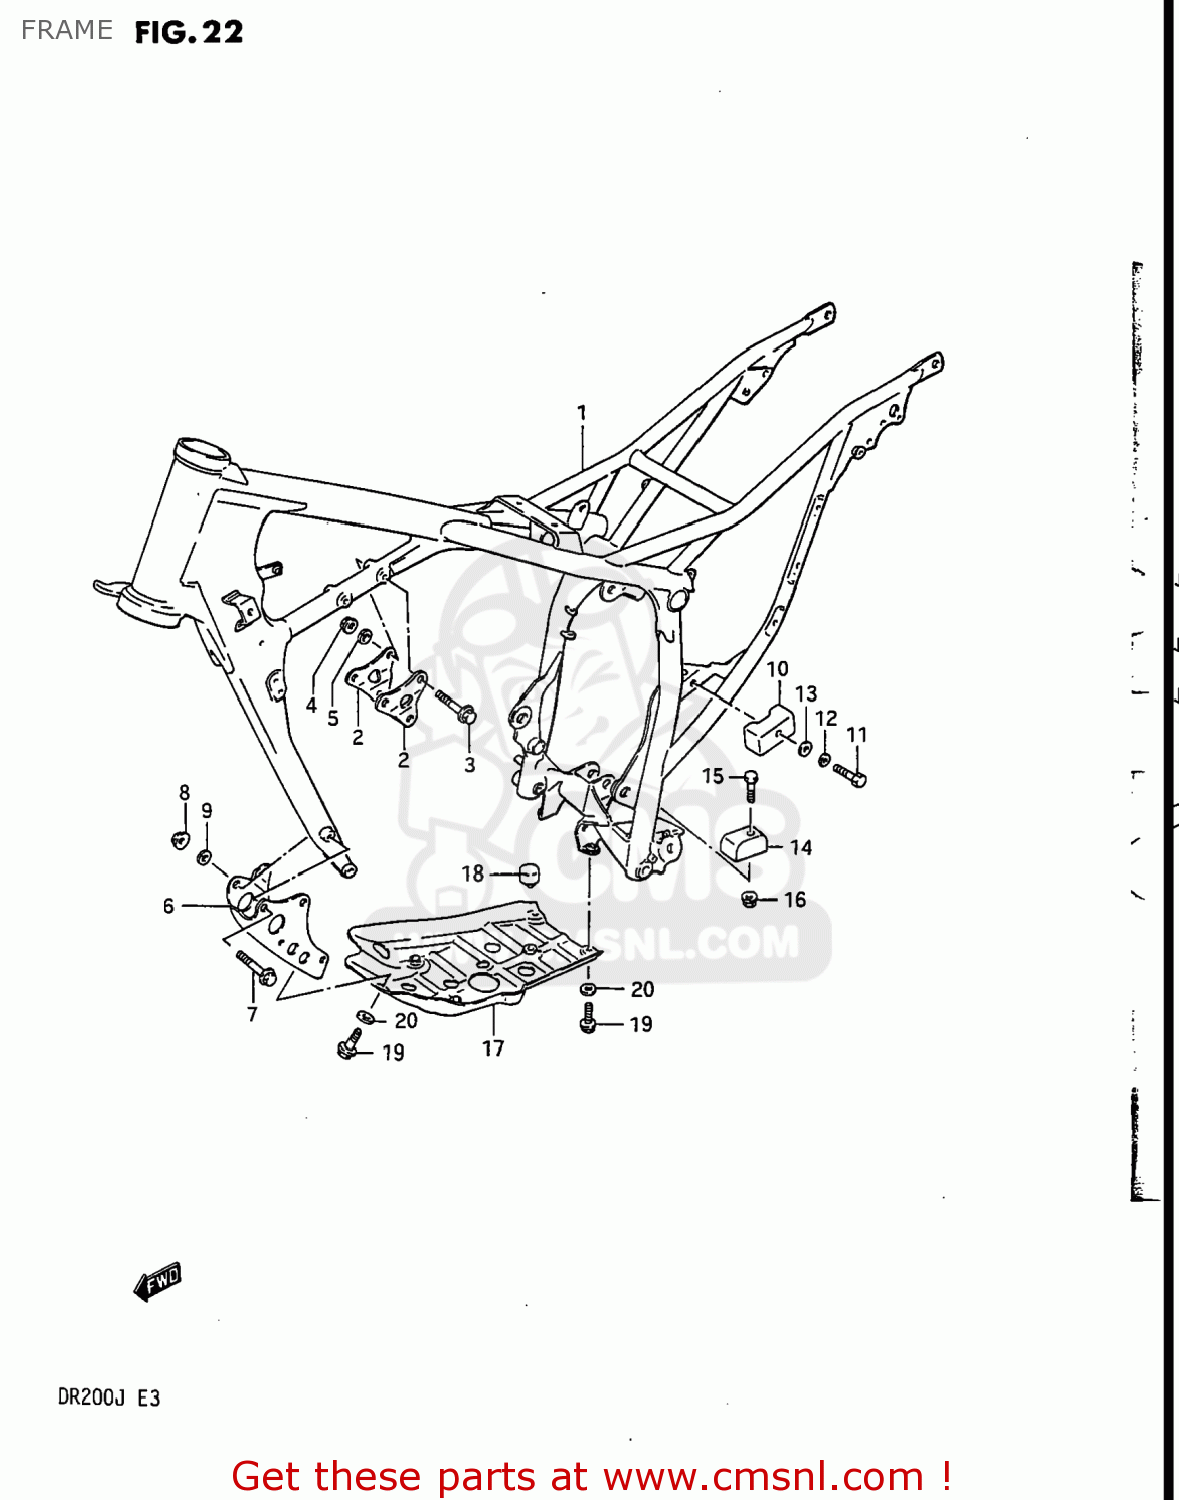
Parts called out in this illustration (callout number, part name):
1	FRAME
2	PLATE,ENGINE MOUNT UPR
3	BOLT
4	NUT
5	LOCK WASHER
6	PLATE,ENGINE MOUNTING
7	BOLT
8	NUT
9	LOCK WASHER
10	GUIDE,CHAIN
11	BOLT 6X35
12	WASHER,LOCK
13	WASHER
14	GUIDE,CH LENGTH CONTROL LWR
15	BOLT
16	NUT 6MM
17	PROTECTOR,ENGINE
18	CUSHION
19	BOLT
20	WASHER
